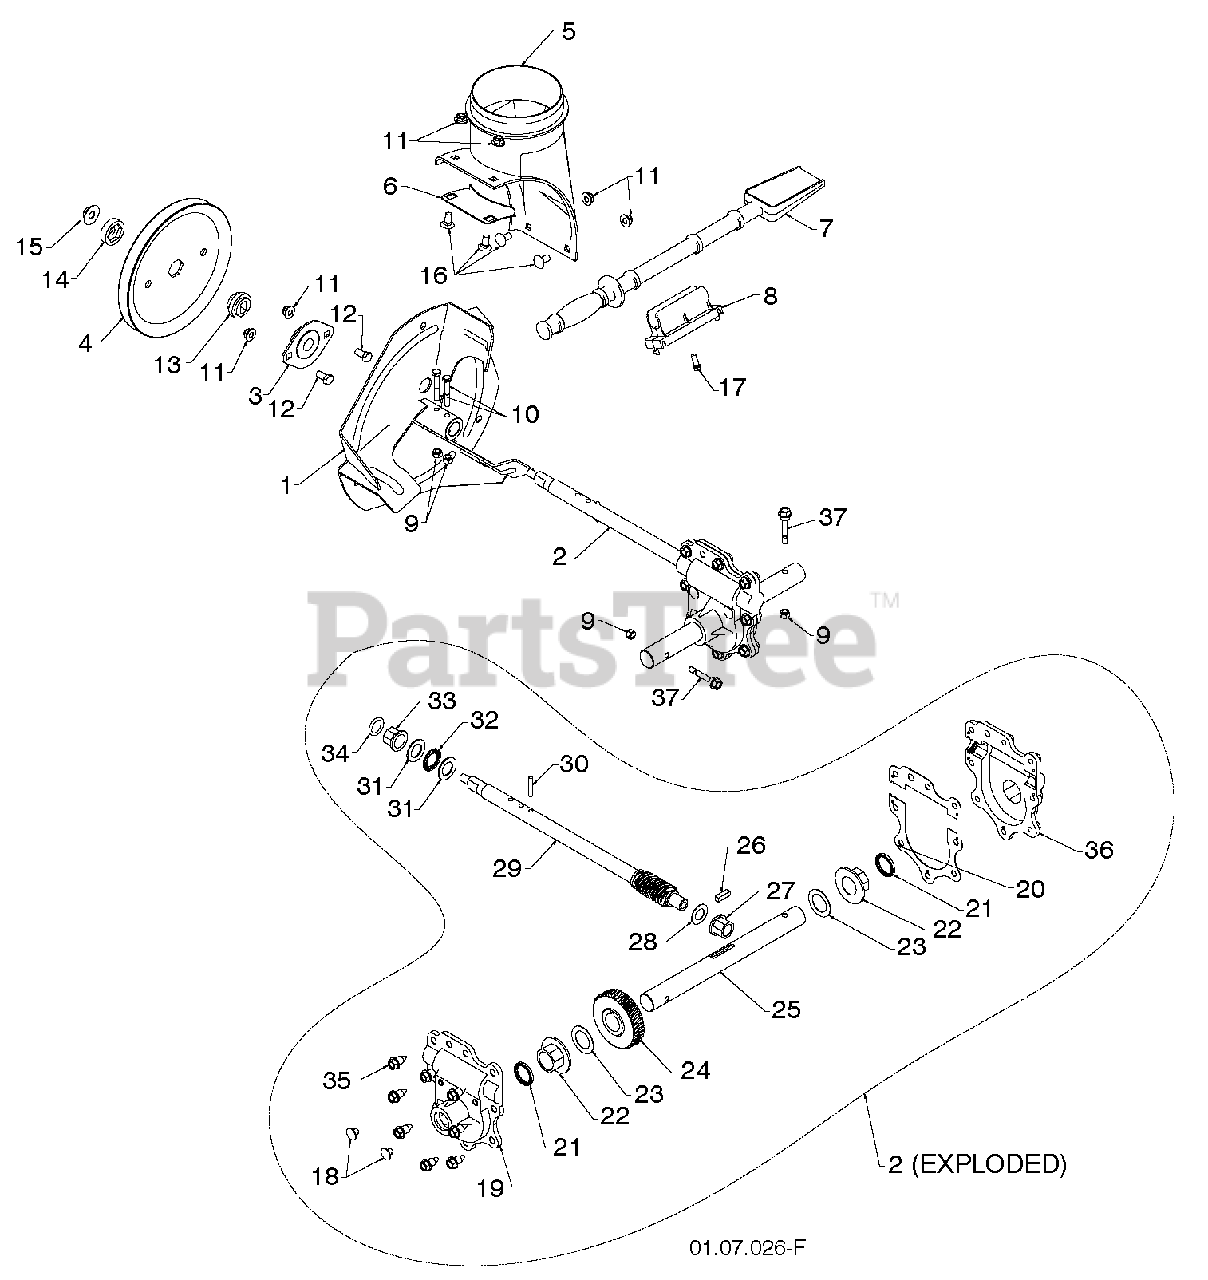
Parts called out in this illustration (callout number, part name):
1	IMPELLER ASSY
2	GEARBOX.ASM.AUGER.D-SHAFT
3	BEARING FLANGE
4	PULLEY.FLANGE.IMPELLER
5	BASE.DISCHARGE.CHUTE
6	BRACKET, CORNER DISCHARGE
7	CLEAN OUT TOOL
8	CLIP.CLEANOUT.TOOL
9	LOCKNUT.NYLOC.1/4-20
10	SCREW.HEX.HD1/4-20X
11	NUTNYLOK.FLRANGE.5/16-18
12	BOLT, HEX HEAD 5/16-18
13	HUB.IMP.PULLEY.D-SHAFT
14	SLEEVE.IMP.PULLEY.D-SHAFT
15	NUT
16	BOLT.CARRIAGE.5/16-18X
17	SCREW.HWH.13-16-5.8.BZP
18	CASE PLUG
19	GEAR.BOX.COVER.RIGHT.SIDE
20	GASKET.GEAR.BOX
21	OIL SEAL
22	FLANGE BUSHING-1"
23	WASHER TRUST 1"
24	WORM GEAR
25	AUGER SHAFT
26	KEY, SQUARE 1/4 X .875
27	FLANGE BUSHING-5/8
28	WASHER, THRUST 5/8
29	SHAFT.IMPELLER.D-SHAFT
30	PIN, ROLL 3/16 X 1-1/8
31	WASHER, THRUST 3/4
32	BEARING TRUST 3/4 NTA-1220
33	BUSHING, FLANGE 3/4
35	HEX SCREW-5/16 X 3/4
36	GEAR.BOX.COVER.LEFT.SIDE
37	BOLT.SHOULDER.SHEAR.1/4-20.
